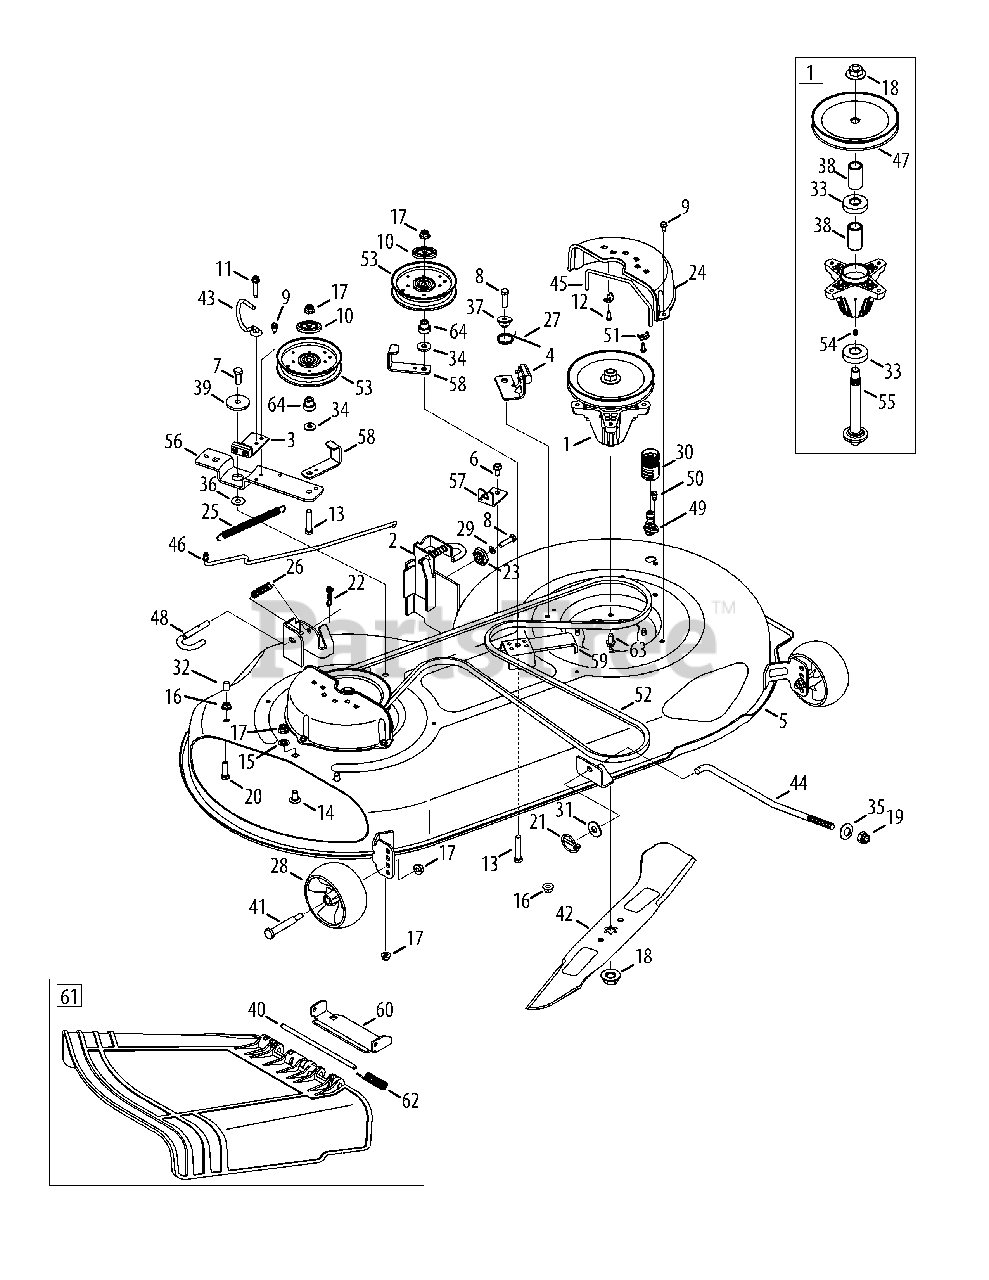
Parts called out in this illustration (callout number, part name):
1	Spindle Ass’y, Pulley, 6.93 Dia
2	Bracket Ass’y, Deck, Hanger LH
3	Brake Ass’y, Deck
4	Brake Ass’y, Deck
5	Deck, Offset, 46" 2W
6	Screw, Self-tapping, 5/16-18, .750,
7	Hex Screw, 3/8-16, 1.00
8	Hex Screw, 5/16-18, 1.25
9	Screw, Self-tapping, 1/4-20, 0.500,
10	Pulley Cap
11	Screw, Self-tapping, 1/4-20, .75,
12	Screw, #10-16:.625
13	Hex Screw, 3/8-16, 2.00
14	Bolt, Carriage, 3/8-16, 0.75
15	Nut, Push, 3/8
16	Nut, Flange Lock, 5/16-18
17	Nut, Flange Lock, 3/8-16
18	Nut, Flange, 5/8-18
19	Nut, Lock, 1/2-13
20	Hex Cap Screw, 5/16-18 x 1.00
21	Pin, Lynch, .1875
22	Bow-Tie Cotter Pin, 72
23	Gear, Deck, Adjustment
24	Belt Cover
25	Spring, Extension, .62 Dia x 6.12
26	Spring, Comp, .535 OD x 1.751
27	Spring, Torsion, .992 I.D x 1.17 O.D
28	Wheel, Deck, 5.0 Dia Ball
29	Washer, Lock, 5/16, Regular Duty
30	Water Nozzle Adaptor
31	Washer, Flat, .531 x 1.25 x .100
32	Cap, .290 x .500
33	Ball Bearing, .787 ID x 1.85 OD x .551
34	Washer, Flat, .385 x .870 x .092
35	Washer, Bell, .63 x 1.25 x .18
36	Washer, Flat, .385 x 1.0 x .030
37	Spacer, Shoulder, .50 x .145
38	Spacer, .792 x 1.060 x 1.860
39	Spacer, Shoulder, .8840 x .190
40	Hinge Pin
41	Bolt, Shoulder, .496 x 2.50, 3/8-16
42	Blade
43	Rod, Keeper, Belt
44	Rod, Lift, Deck, Frt, 13.7
45	Rod, Keeper, Belt
46	Rod, Control, Brake
47	Pulley, Deck, 6.93 Dia
48	Rod, Handle, Deck Release
49	Deck Wash Nozzle
50	Shoulder Screw, 1/4-20 x 0.50
51	Clamp, Casing
52	Belt, V-Type
53	Pulley, Idler, 4.25"Dia
54	Fitting, 3/16, Lnc#70, Drive Lube
55	Shift, Spindle, 6.11.
56	Bracket, Idler, Pivot
57	Bracket, Cable, Deck Engage
58	Bracket, Guard, Belt, 4.25 Pulley
59	Bracket, Support, Deck Stationary Idler
60	Bracket, Chute
61	Chute Ass’y, Deflector
62	Torsion Spring, .44 ID x 2.0
63	Self Tapping Screw, 5/16-18 x .75
64	Shoulder Spacer
